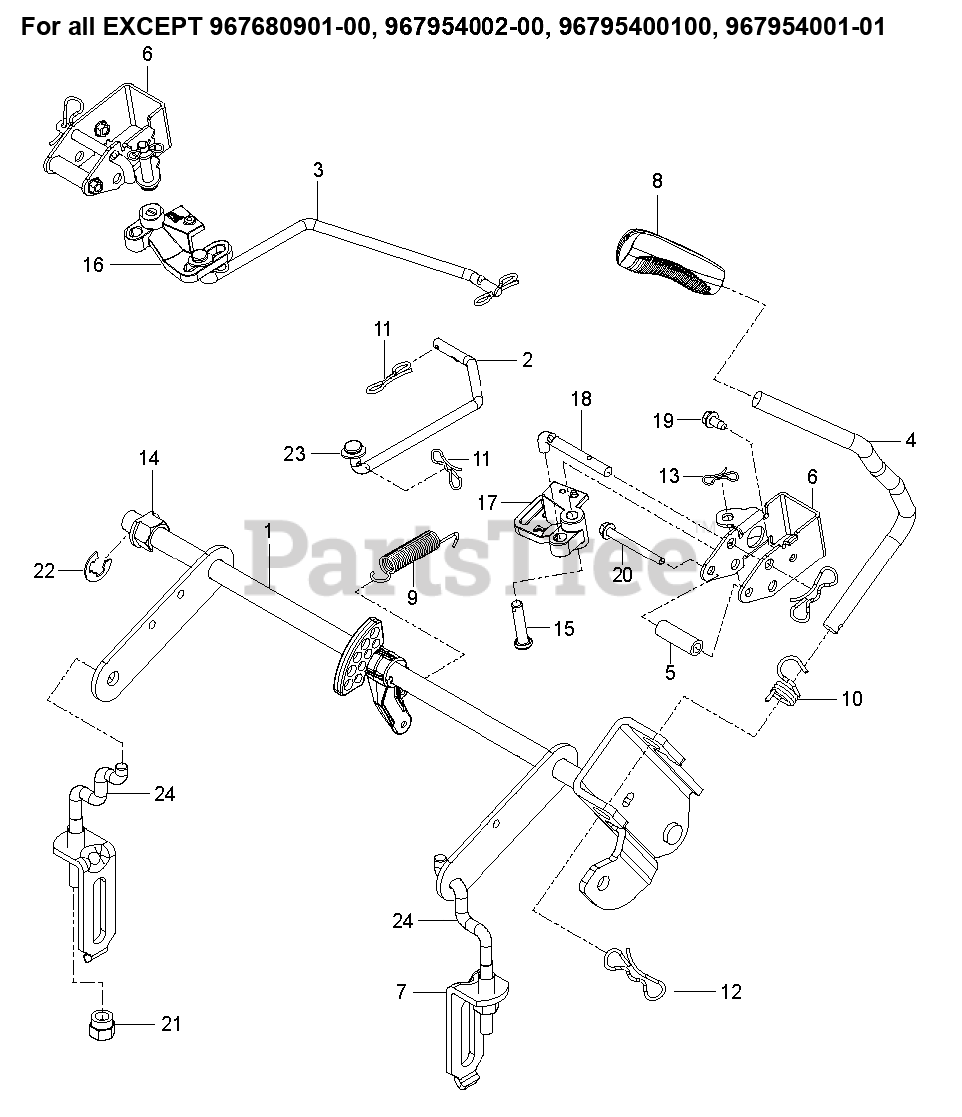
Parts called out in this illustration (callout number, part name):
1	SHAFT.ASM.RZ.DECK.LIFT.SRV
1	SHAFT ASSY DECK LIFT WELDMENT
2	LINK.BRAKE.PARK.UPPER.LH
3	LINK.BRAKE.PARK.UPPER.RH
4	LIFT.LEVER.ASM.RZ.SERVICE
4	HANDLE LIFT ZTR
5	SPACER.334.ID.5.OD.1.5.L
6	BRACKET.BELLCRANK.PBRAKE X431
7	ASSEMBLY, BRKT LINK
7	LINK.ASM.RZ.LIFT.SERVICE
8	GRIP.HANDLE.LIFT.PVC.BLACK
9	RETURN.BRAKE.PARK.AUTO
10	SPRING.TORSION.LIFT.HANDLE
11	PIN COTTER;LOCKING;BOWTIE;1IN
12	PIN.COTTER.7/16.BOW TI.
13	PIN.COTTER.5/16.BOW TI
14	PLASTIC NUT
15	PIN.5.16X1.5
16	BELLCRANK.RH
17	BELLCRANK.LH
18	ROD.PUSH.BRAKE
19	SCREW.1/4-20X5/8
20	SCREW THD;ROLL;1/4-20 X 2.25
21	NUT, LIFT LINK 7/16-20
22	RETAINING RING LT
23	WASHER
24	LINK, REAR SUSPENSION
